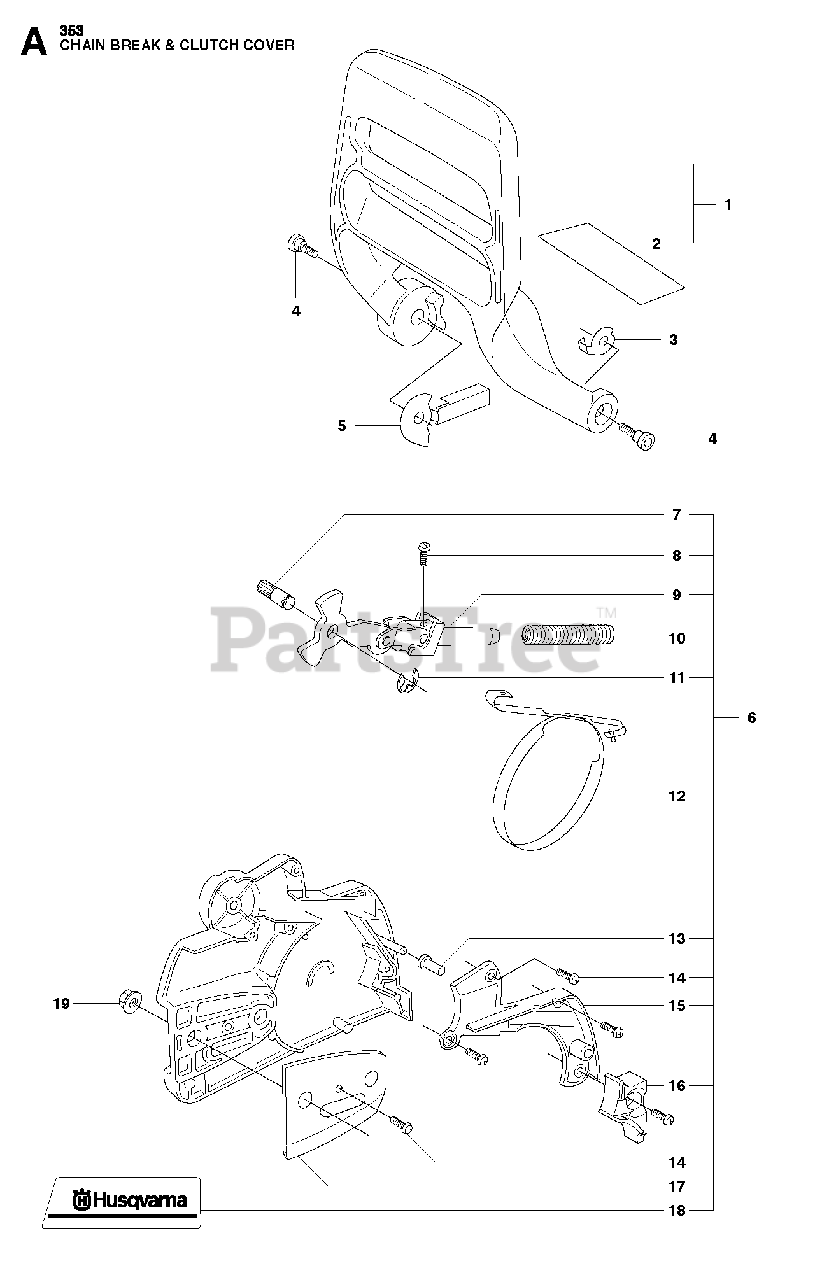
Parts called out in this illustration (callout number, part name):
1	CHAINBRAKE HANDLE
2	PROTECTOR
3	WASHER
6	CHAIN BRAKE
7	PIN
8	SCREW
9	JOINT
10	SPRING
11	E-RING 4
12	BRAKE BAND
13	SLEEVE
14	SCREW
15	COVER
16	PROTECTOR
17	PLATE
18	DECAL
19	NUT M8 FLANGE
